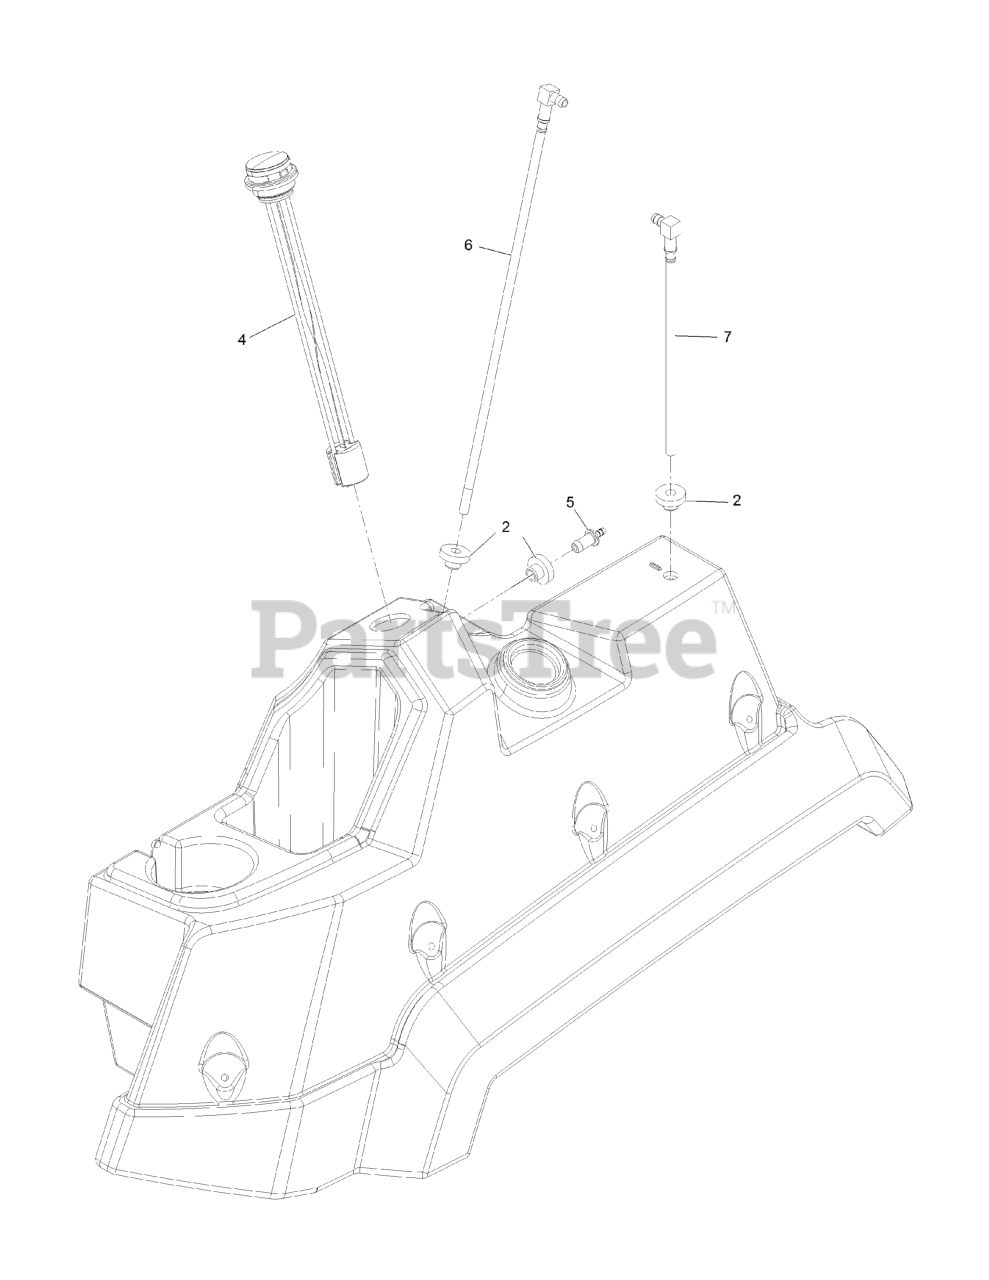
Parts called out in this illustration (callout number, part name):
2	BUSHING
4	GAUGE-FUEL
5	FITTING-ORIFICE, STRAIGHT
6	PICK-UP-FUEL
7	RETURN-FUEL
